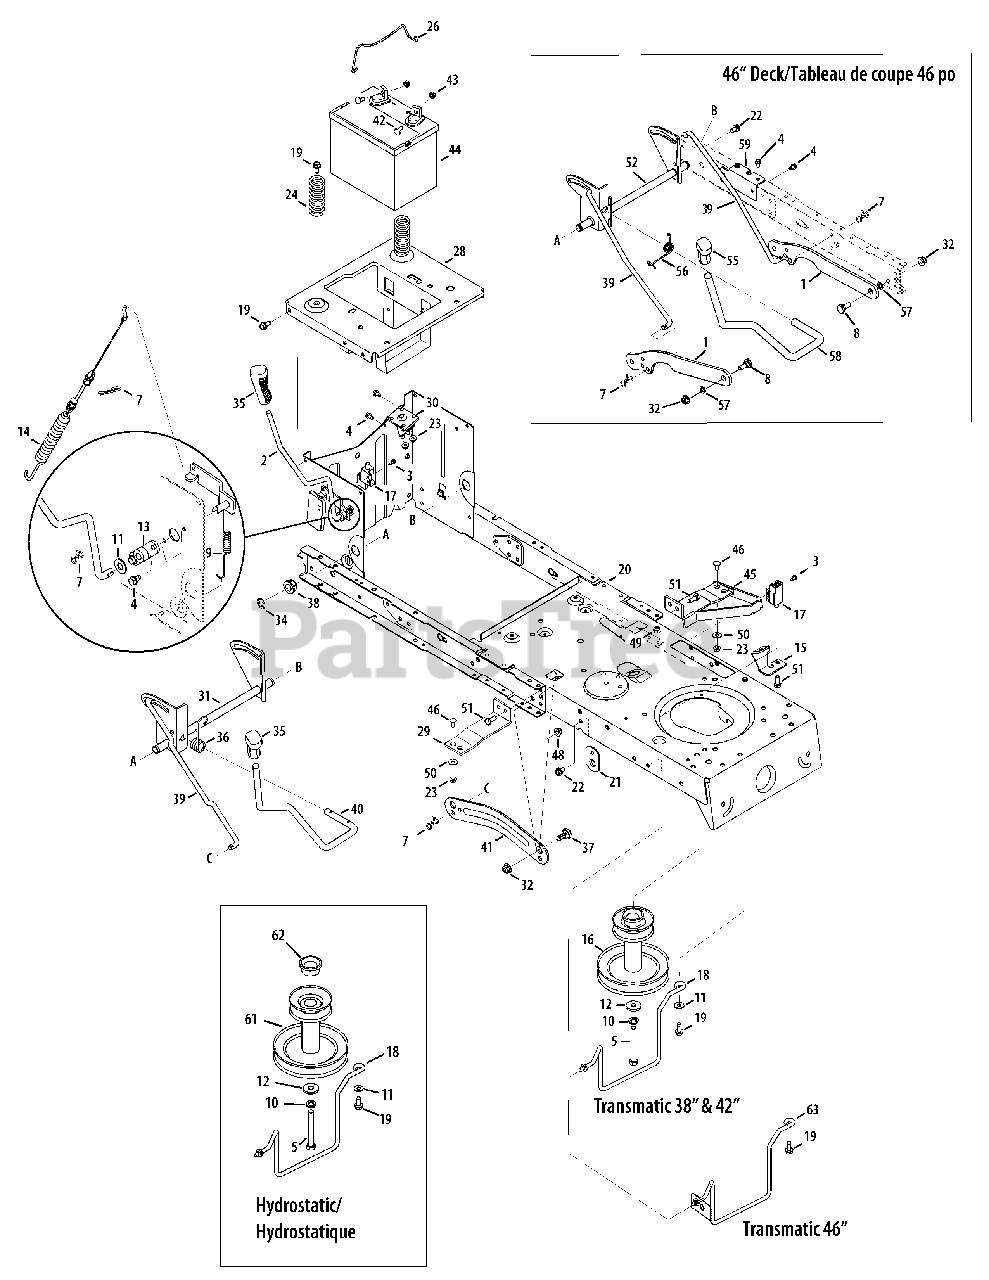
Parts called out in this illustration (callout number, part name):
3	Shoulder Screw #10-16 x .50" Lg.
4	Hex Wash S-Tapp Screw 1/4-20 x .50
5	Hex Hd. Cap Screw. 7/16-20 x 3.25 Gr. 5 (38/42")
7	Bow Tie Cotter Pin
8	Shoulder Screw .5 x .270 : 3/8-16
9	Extension Spring
10	Lockwasher 7/16 ID
11	Flat Washer .385 ID x .87 OD x .06 (38" only)
12	Flat Washer .450 x 1.25 x .164
14	Deck Engagement Cable
16	Engine Pulley 3.39 x 6.12 dia. (38/42")
17	Interlock Switch
18	Belt Keeper Rod (38" Deck)
19	S-Tapp Screw 5/16-18 x .75
22	Hex Wash HD TT Screw 5/16-18 x .625
23	Hex L-Flanged Nut 1/4-20 Gr. F, Nylon
24	Compression Spring 1.28 x 3.125
26	Battery Hold Down Rod
28	Seat Frame Bracket
30	Solenoid
32	Flange Lock-Nut 3/8-16 Gr. F, Nylon
34	"E" Ring .625 Dia.
36	Torsion Spring (38" & 42")
37	Shoulder Screw .625 x .175, 3/8-16
38	Hex Flange Bearing .630 ID
40	Deck Lift Handle(38")
40	Deck Lift Handle(42")
42	Hex Flg. Screw. 1/4-20 x .75 Gr. 5
43	Sems Hex Nut 1/4-20
44	Battery 245 CCA (Dry)
46	Carriage Bolt 1/4-20 x .62
48	Hex L-Flg Nut 5/16-18 Gr. F, Nylon
49	Hex L-Nut 5/16-18
50	Flat Washer .28 x .74 x .063
51	Hex Screw 5/16-18 x .75
52	Lift Shaft (46" only)
56	Torsion Spring (46")
57	Flat Washer .395 x .62 x .063
58	Deck Lift Handle (46")
59	Brace Bracket
61	Engine Pulley 3.39 x 6.12 dia. (38/42")
62	Spacer 1.0 x 1.4 x .825
63	Belt Keeper Rod (46" Deck)
